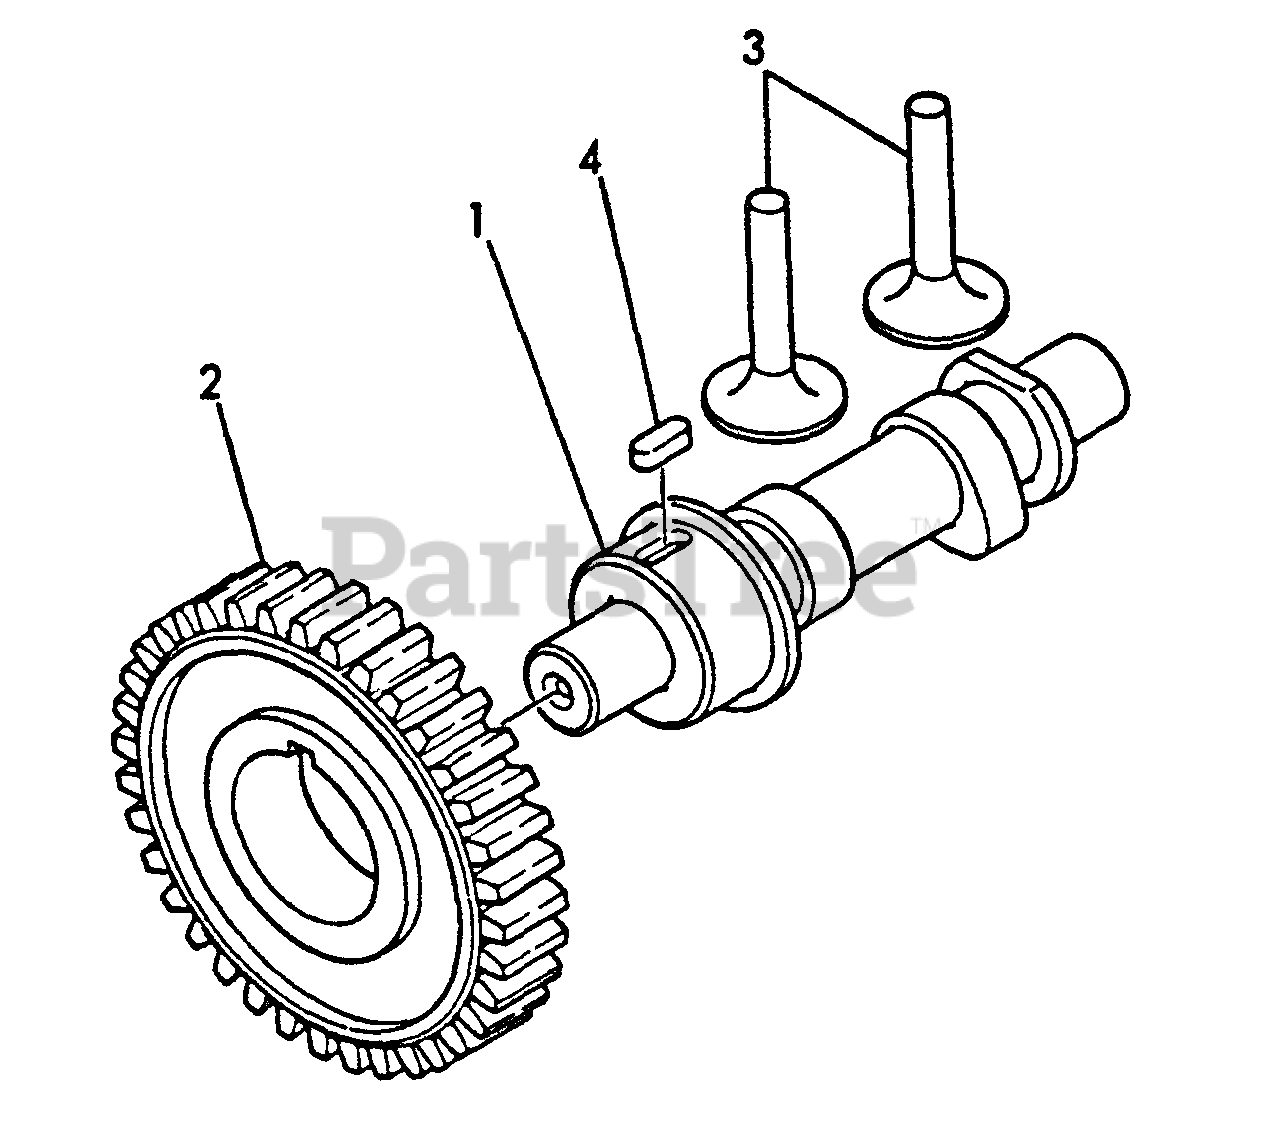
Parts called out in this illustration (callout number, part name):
1	CAMSHAFT
2	GEAR, CAMSHAFT
3	TAPPET
4	KEY - 4X10
